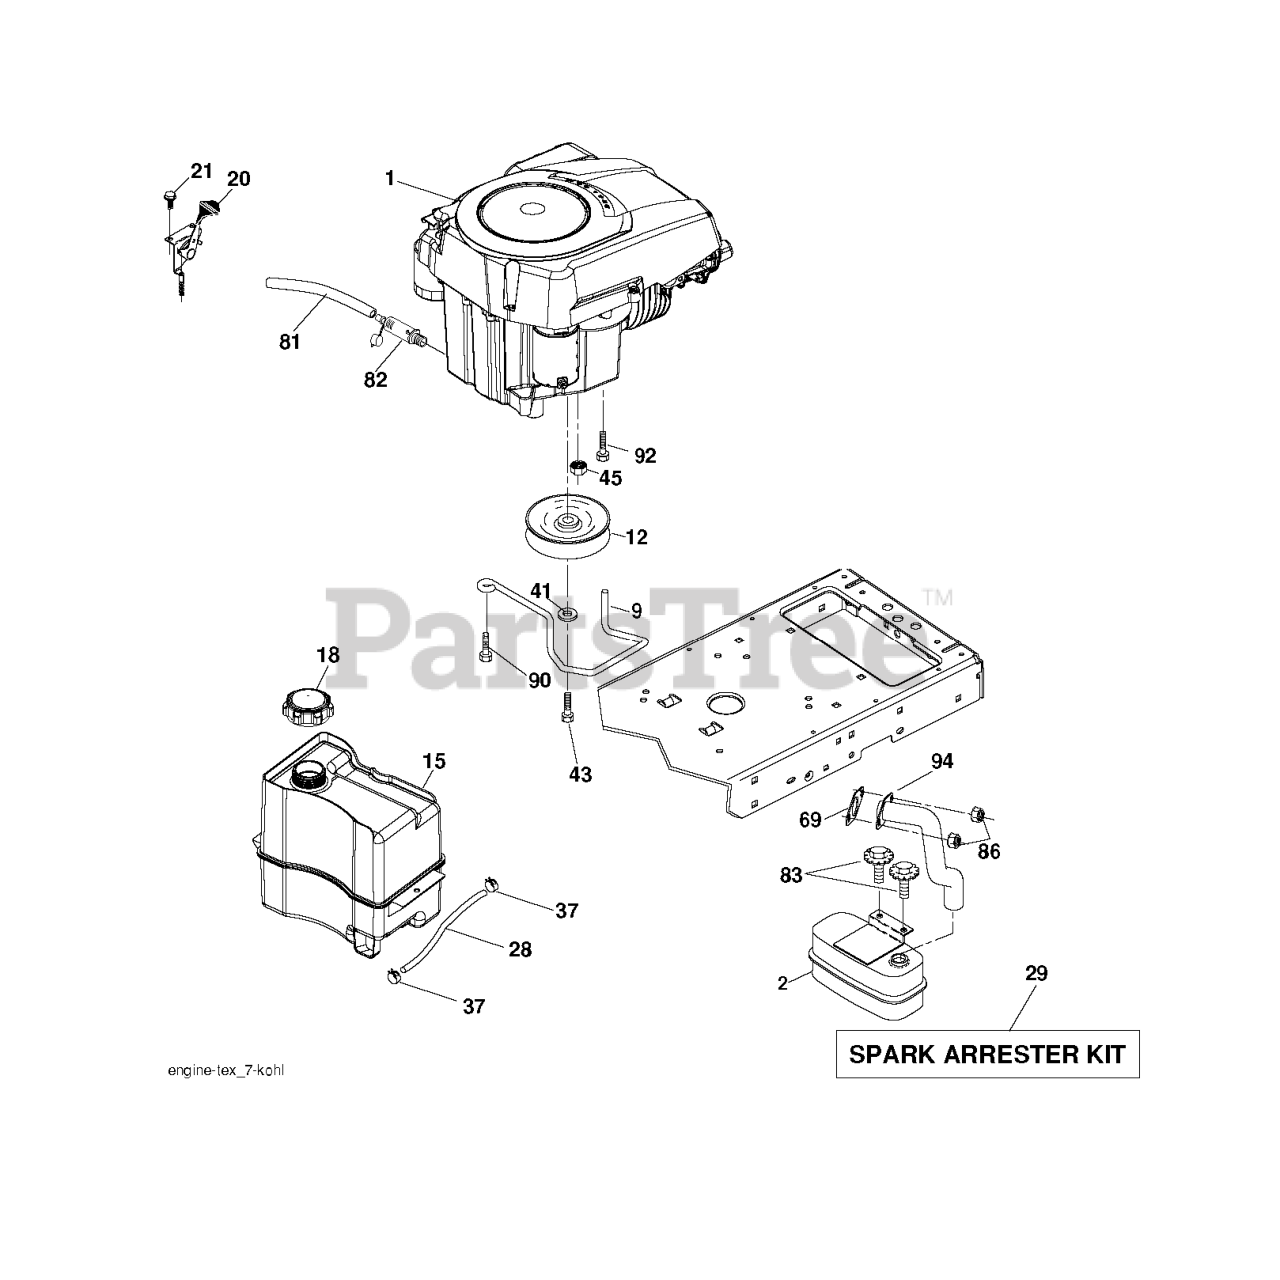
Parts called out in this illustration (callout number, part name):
2	MUFFLER.SINGLE.CYL.KOHL/B&S
9	KEEPER.BELT.ENGINE.3.25 (3 2)
12	PULLEY ENGINE
15	RP TANK FUEL FRT 1.5 GAL
18	FUEL CAP
20	CONTROL.TH/CK.C.
21	SCREW
28	LINE.FUEL.20
29	KIT.SPARK ARRESTOR 794945 B&S
37	HOSE CLAMP
41	LOCKWASHER
43	BOLT HEX 7/16-20X4-1/4"
45	NUT
81	Tube Drain Oil Easy
82	Plug Drain Oil
83	BOLT.5/16-18UNCX3/4 W/SEMS.BLK
86	NUT.HEX.FLANGE.TOPLOCK
90	SCREW 3/8-16X1
92	SCREW 3/8-16X1
94	RP.TUBE.EXHAUST.KOHL.COURAGE
97	SCREW HEXWSHR 1/4-20X3/4
